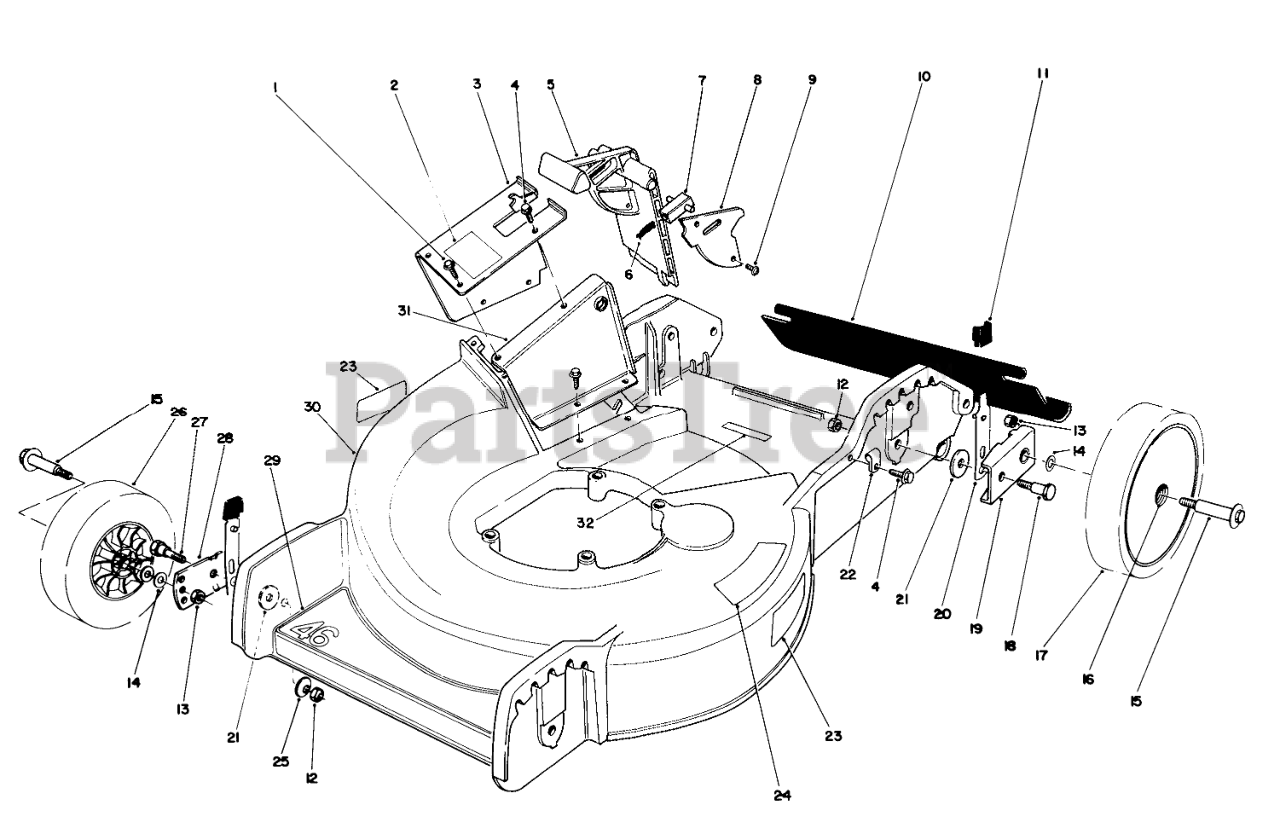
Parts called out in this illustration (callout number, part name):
1	SCREW
2	DECAL - DANGER
3	Tunnel-Outer (Incl. Ref. #2)
4	SCREW
5	Door Mulching
6	SPRING-COMPRESSION, LATCH
7	Door Latch
8	Cover Door
10	SHIELD - TRAILING
11	KNOB-ARM
12	NUT-LOCK, NI
13	Nut
14	WASHER
15	BOLT-WHEEL
16	BUSHING
17	Wheel & Tire Assembly (Incl. Ref. #16)
18	PIVOT SCREW
19	PIVOT ARM ASM
20	SPRING ARM ASM
21	PIVOT WASHER
22	CLAMP-CABLE
23	Decal Danger
24	DECAL - STEP PAD INT'L
25	WASHER-BELLEVILLE
26	Wheel & Tire Assembly (Inc. Ref. #16)
27	5/16-18 PIVOT SCREW
28	PIVOT ARM ASSY
29	DECAL - DECK
30	Housing(Incl. Ref. #23)
31	Tunnel-Inner
32	Decal
